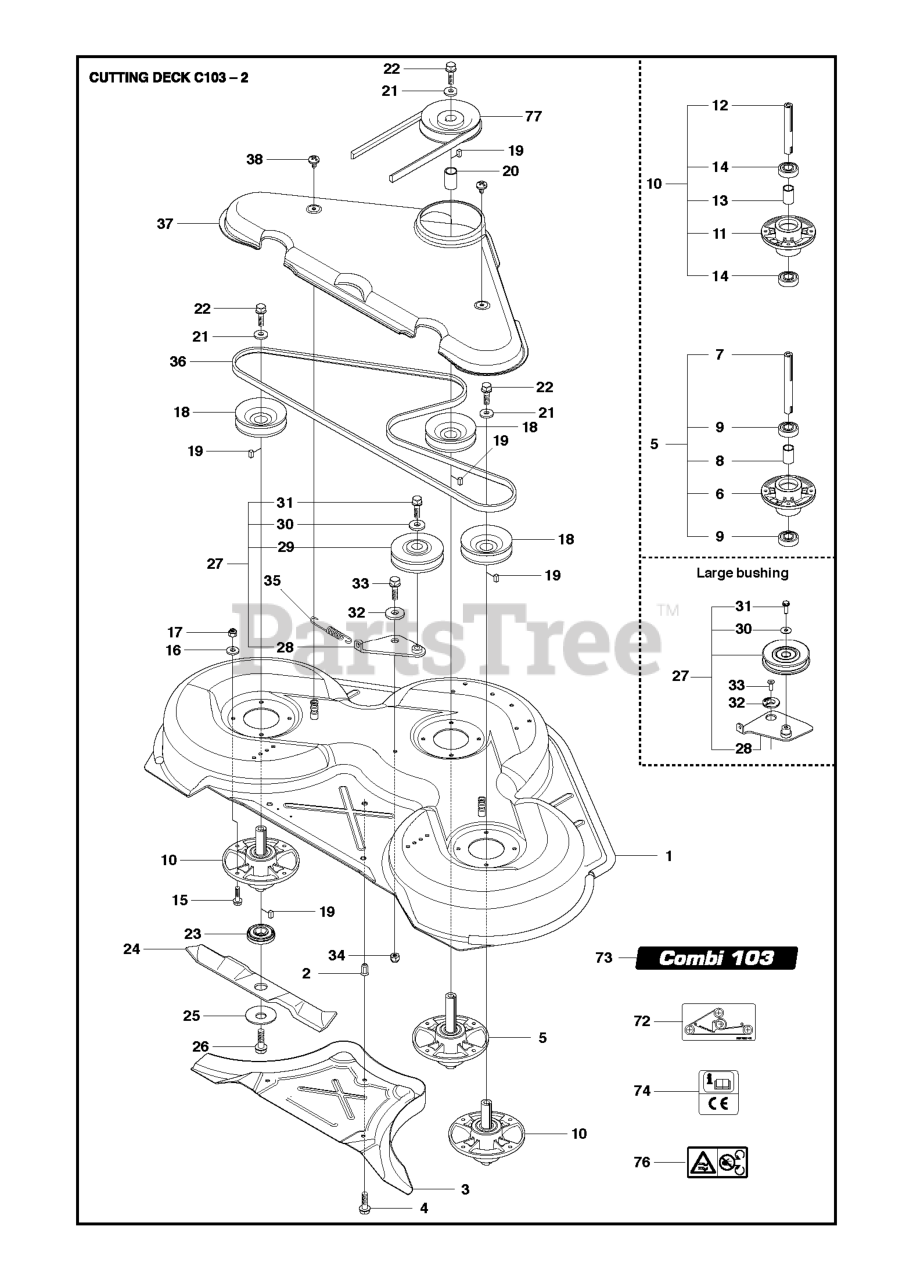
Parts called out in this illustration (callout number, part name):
6	BEARING HOUSING
8	SPACING SLEEVE
10	BLADE HOUSING ASSY
11	BEARING HOUSING
13	SPACING SLEEVE
16	WASHER BRB 8.4X17
17	LOCKNUT M8
20	SPACING SLEEVE
25	WASHER
27	BELT TENSIONER ASSY
27	Belt Tensioners
28	BELT TENSIONING ARM
31	BOLT
32	WASHER SHOULDER ASSY
32	WASHER
33	SCREW
34	LOCKNUT M8
